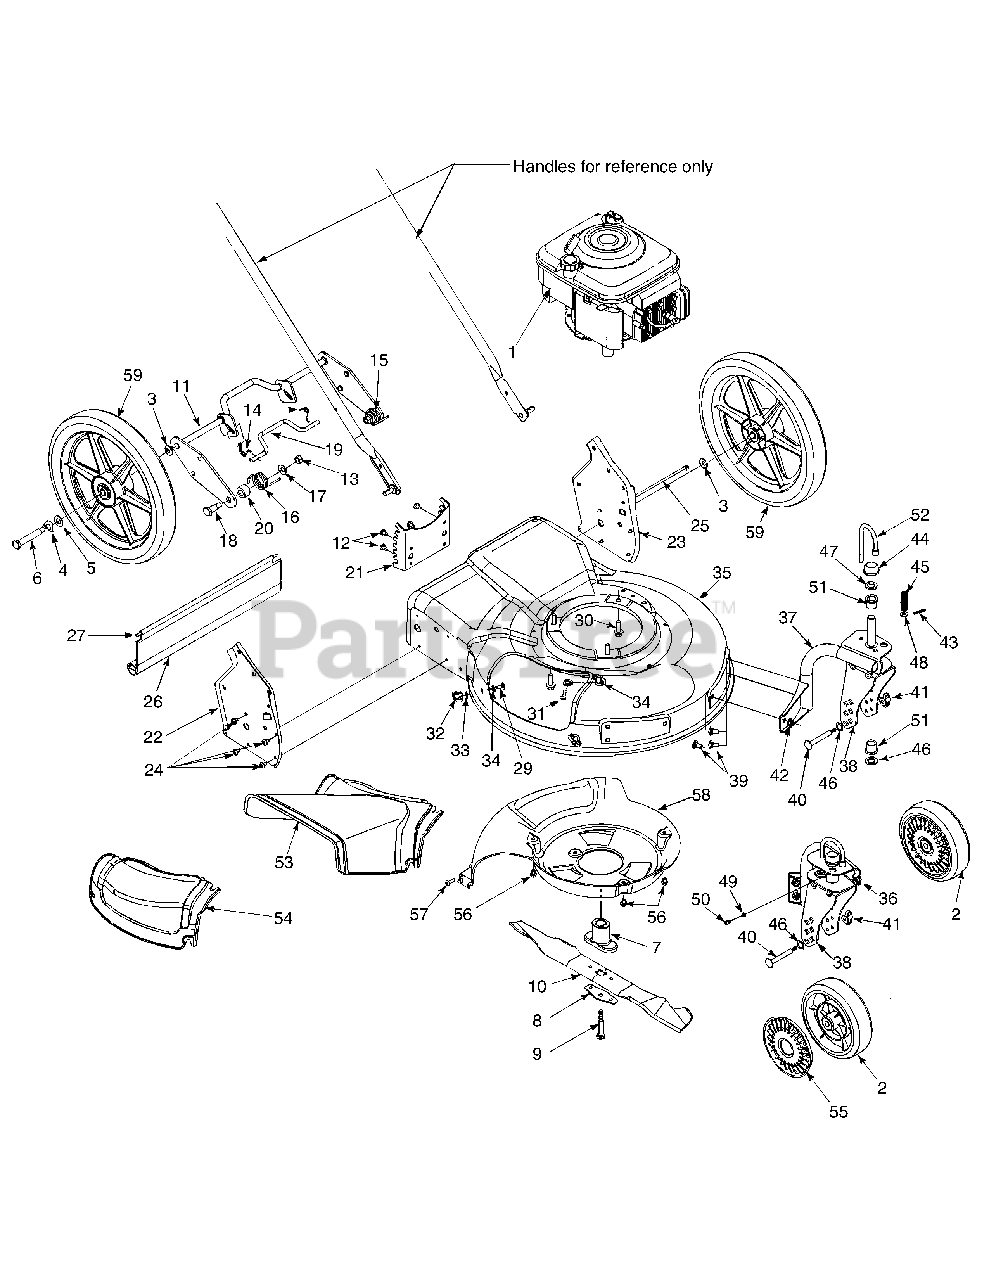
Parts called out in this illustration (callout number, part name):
1	Engine
2	Wheel, Front Caster 7 X 2
3	Bell Washer .401 X .870 X .063
4	Spring Washer .50 I.D. x 1.0 O.D.
5	Flat Washer .510 x 1.0 x .060
6	Shoulder Screw .500 x 2.62: 3/16
7	Blade Adapter
8	Blade Bell Support
9	Hex Bolt 3/8 - 24 x 2.5 Gr. 8
10	Blade 21", Mulching
11	Hi-Wheel Height Adj. Support
12	AB Screw 1/4-14 x .50
13	Hex Nut 3/8 -16
14	Torsion Spring
15	Torsion Spring, RH
16	Torsion Spring, LH
17	Bell Washer .401 x .870 x .063
18	Shoulder Screw .500 x .840
19	Handle, Height Adjustment
20	Spacer .500 x 1.0 x .600
25	Cable Tie
26	Trail Shield
27	Trail Shield Wire
29	Carriage Screw
30	TT Screw 3/8 -16 x 1.00
31	Carriage Screw 1/4-20 x .75
32	Wing Nut
33	Push Nut
34	Flat Washer
39	Carriage Bolt 5/16-18 x .62
40	Caster Axle .374 x 2.59
41	Wing Nut
42	Flange Nut 5/16-18 Gr.5
43	Hairpin Clip
44	Push Cap
45	Compression Spring
46	Wave Washer .530 I.D. x .78 O.D.
48	Flat Washer .330 I.D. x .630 x .06
49	Fl.Wash. .203 I.D. x .403 x .040
50	Lube Fitting
51	Flange Bearing
52	Lock Pin, Front Wheel
53	Discharge Chute
54	Mulching Cover
55	Hubcap
56	Hex Screw, TT 1/4-20 x .375
57	HL Screw
58	Rear Baffle
59	Hi-Wheel 14 X 2
